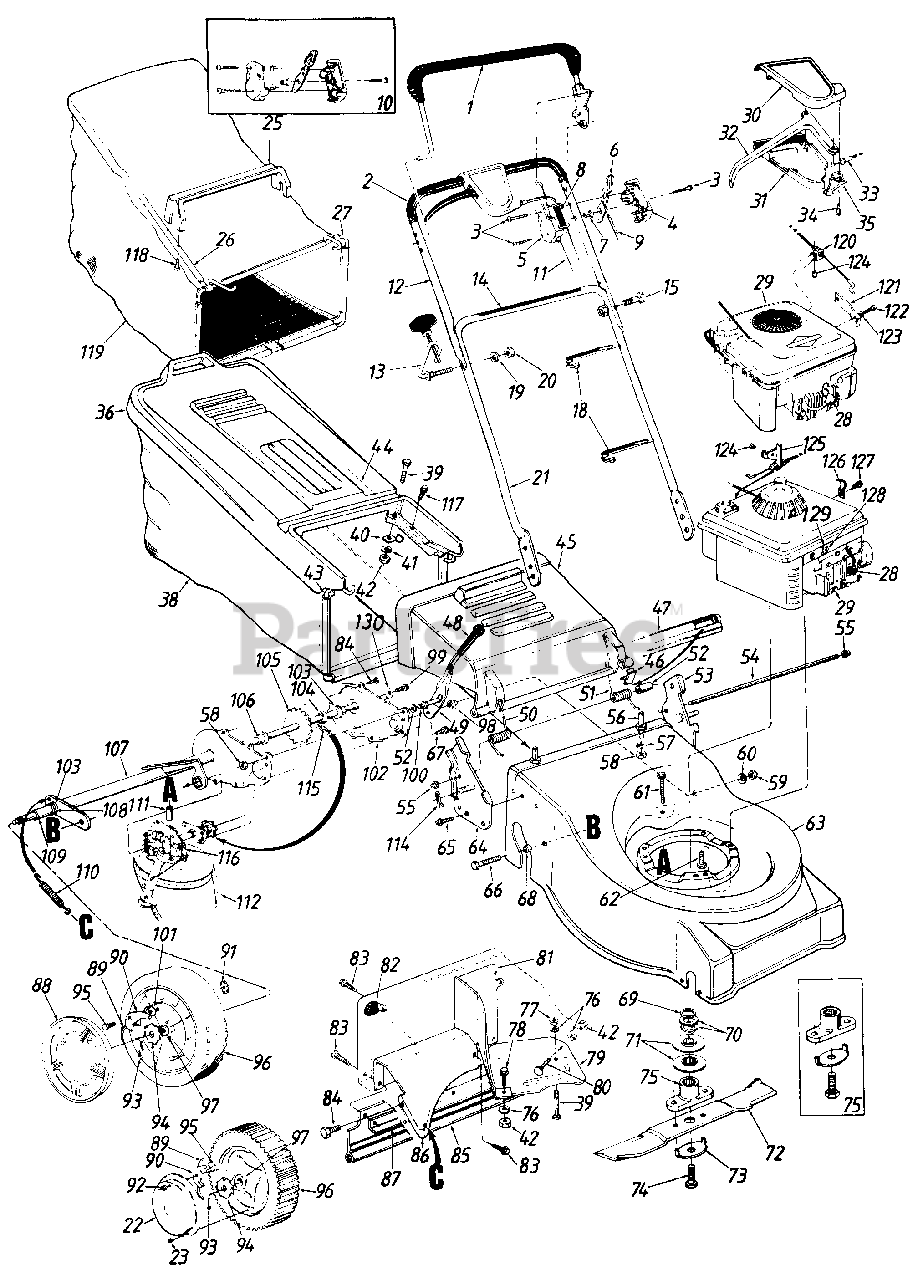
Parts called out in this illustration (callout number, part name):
1	Control Handle Ass'y.
2	Grip
3	Truss Mach. B-Tap Scr. #12 x 1.5" Lg.
4	Control Panel Half
5	Clutch Panel Half
6	Throttle Control Lever
7	Control Disc Pin
8	Control Label-Throttle
9	Throttle Wire-53" Lg.
10	Control Housing Comp.
11	Control Cable-46" Lg.
12	Upper Handle
13	Rope Guide Bolt
14	Instruction Label-Handle
15	Curved Carriage Bolt 5/16-18 x 1.38" Lg.
18	Cable Tie
19	L-Wash. 5/16" I.D.
20	Hex Nut 5/16-18 Thd.
21	Lower Handle
22	Hub Cap
23	Pan HD. Tap Scr. #12 x .50" Lg.
25	Bag Handle
26	Rear Catcher Frame
27	Front Catcher Frame
28	Spark Plug Boot
29	Engine
30	Control Cover Half-Upper
31	Control Cover Half-Lower
32	Control Lever
33	Drive Cable-53" Lg.
34	Flat C-Sunk Hd. Tap Scr. #10 x .75" Lg.
35	Cable Mtg. Cap
36	Hardtop Bag Cover
38	Grass Bag
39	Truss Mach. Scr. 1/4-20 x 1.0" Lg.
40	Mounting Clamp
41	Fl-Wash. .281" I.D. x .62"
42	Hex Nut 1/4-20 Thd.*
43	Front Catcher Frame
44	Rear Catcher Frame
45	Chute Deflector
46	Deflector Plug
47	Seal-Extrusion
49	Spring Lever
50	Torsion Spring-R.H.
51	Torsion Spring-L.H.
52	Spacer.255" I.D.
53	Handle Brkt. Ass'y.-L.H.
54	Hinge Pin 17.75" Lg.
55	Cap Speed Nut
56	Shld. Pin 3/8-24 x 1.43" Lg.
57	L-Wash. 3/8" I.D.*
58	Hex Jam Nut 3/8-24 Thd
59	Hex L-Nut 3/8-24 Thd.
60	Bell-Wash. .38" I.D. x .88"
61	Hex Wash. Hd. Tap Scr. 1/4-20 x 1. 5 " Lg .
62	Hex L-Wash. Hd. Scr. 3/8-16x 1" Lg.
63	21" Deck Ass'y.
64	Handle Brkt. Ass'y.-R.H.
65	Hex L-Wash. Hd. AB-Tap Scr. 1/4 x.62" Lg.
66	Hex Wash. Hd. Tap Scr. 3/8-16 x .75" Lg .
67	Hex Wash. Hd. Tap Scr. 1/4-20 x .5" Lg.
68	Spacer.385" I.D.
69	Serrated Washer 1.0" I.D.
70	Wave Washer 1.005" I.D.
71	Serrated Pulley Half
72	21" Blade
73	Blade Bell-Wash. .44" I.D.
74	Hex Bolt 7/16-20 x 1.5" Lg. (Grade 5)
75	Blade Adapter Kit
76	L-Wash. 1/4" I.D.*
77	Hex Jam Nut 1/4-20 Thd.
78	Hex Bolt 1/4-20 x .85" Lg.
79	Rear Belt Baffle
80	Carr. Bolt 1/4-20 x .50" Lg.*
83	Torx Mach. AB-Tap Scr. 1/4 x .62" Lg.
84	Hex B-Tap Scr. 1/4 x .38" Lg.
85	Rear Flap
89	Plastic Spring
90	Pawl.345" I.D.
91	Weld Nut 1/4-20 Thd.
92	Hex Ins. L-Nut 1/4-20 Thd.
93	Cotter Pin 1/8" Dia.
94	Ratchet Wheel 1.62" O.D.
95	Shld. Bolt .342" Dia. x .268"
96	Wheel Ass'y. Comp.-Rear
97	Flange Ball bearing 1/2" I.D.
98	Shld. Spacer. 50" Dia.
99	Hex Bolt 1/4-20 x .62" Lg. (Grade 5)
100	Shld. Pin 3/8-24 x 1.43" Lg.
101	Bell-Wash. .265" I.D. x .75"
102	Chain Cover Ass'y.
103	Hex Flange Brg. .506n I.D.
104	Fl-Wash. .531" I.D. x .93"
105	Rear Axle Ass'y.
106	Hex Flange Bearing
109	Spacer. 513" I.D.
110	Extension Spring 3.8" Lg.
111	Spacer.325" I.D.
112	V-Belt
114	Internal Cotter Pin 5/16n Dia.
115	#48 Chain .50" Pitch x 30 Links
116	Transmission Comp.
117	Hex AB-Tap Scr. 1/4 x .62" Lg.
118	Hex AB-Tap Scr. #12 x 1.25" Lg.
119	Grass Bag
120	Cable Mtg. Brkt.
121	Mounting Brkt.
122	Truss Mach. Scr. #10 x .5" Lg.
123	L-Wash. #10 I.D.
124	Pop Rivet .156" Dia.
125	Cable Brkt.
126	Cable Clamp
127	Hex B-Tap Scr. #10 x .38" Lg.
128	Hex B-Tap Scr. #10 x .62" Lg.
129	Cable Clamp
130	Bell-Wash. 1/4" I.D.
